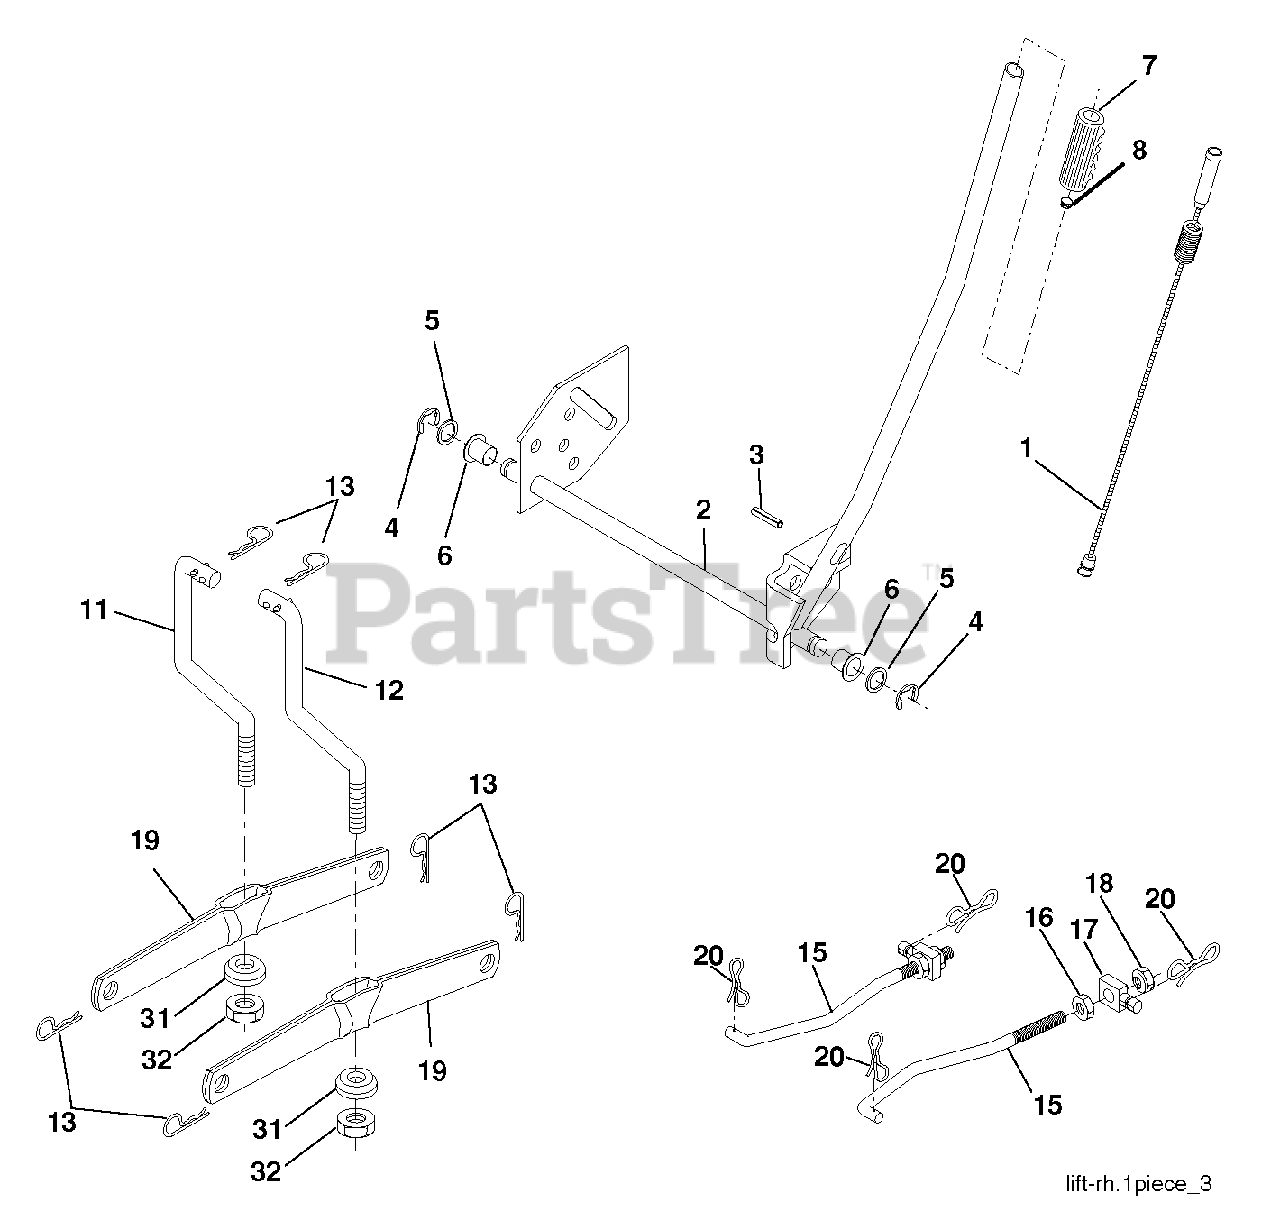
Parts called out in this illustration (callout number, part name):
1	PLUNGER.ASM.LIFT.LEVER.BLK.
2	SHAFT.ASM.LIFT.YT
3	PIN.GROOVE.5/16
4	RETAINING RING LT
6	BEARING.NYLON
7	GRIP HANDLE
8	PLUNGER BUT KIT
11	LINK LIFT LH
12	Lift Link Assembly, RH
13	RETAINER-SPRNG RB
15	LINK.SUSPENSION.FRONT
16	NUT.HEX.JAM.1/2-13
17	TRUNNION
18	NUT.LK.W/WSH.1/2.
19	ARM.REAR.SUSPENSION
20	PIN.COTTER.7/16.BOW TI.
31	BEARING.PIVOT.LIFT
32	NUT CROWNLOCK 3/8-24
